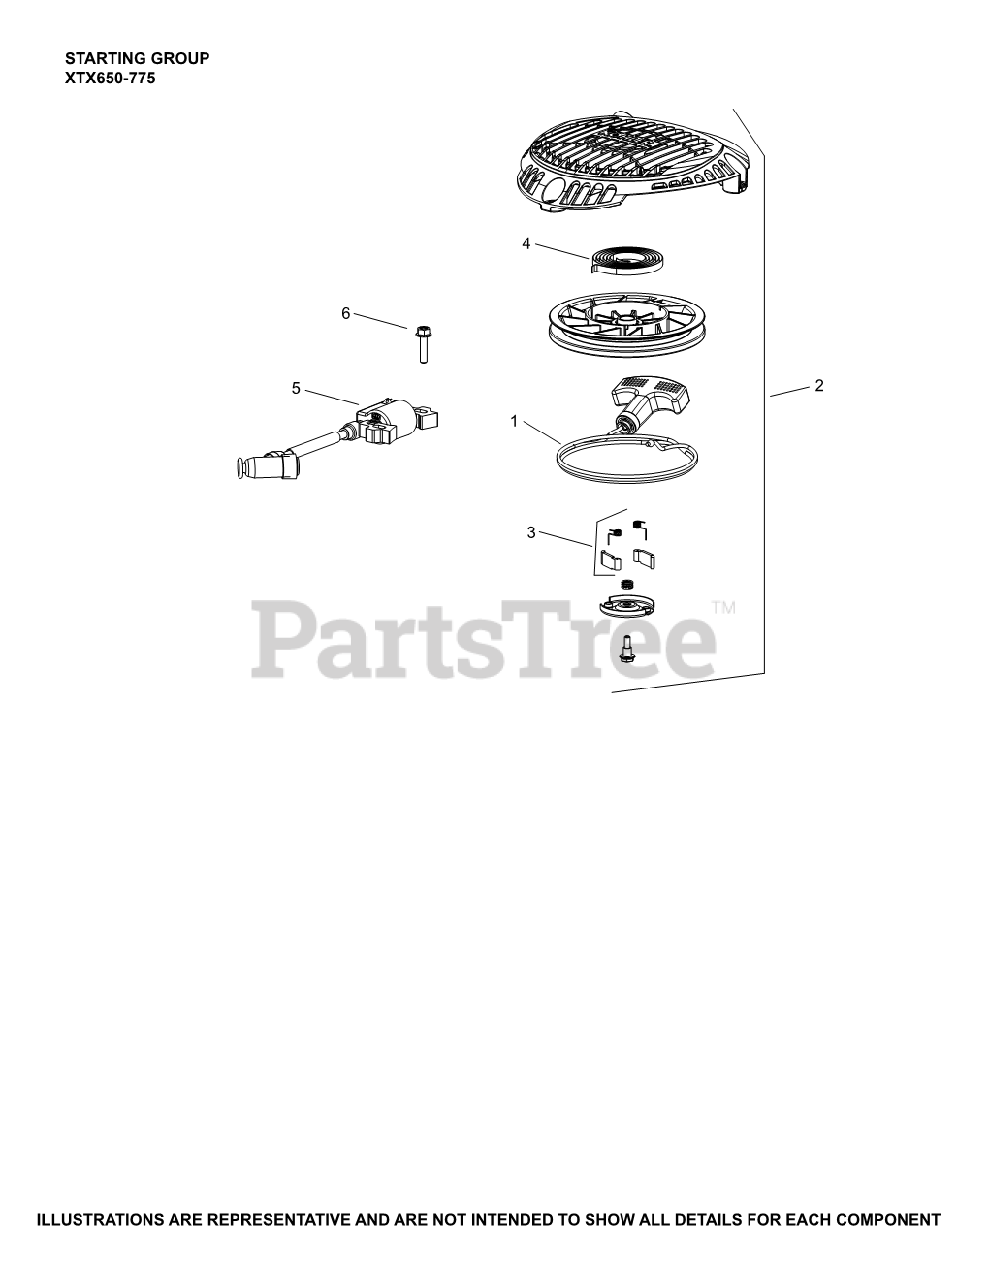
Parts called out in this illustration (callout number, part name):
1	KIT, STARTER ROPE W/HANDLE
2	STARTER ASSY-RETRACT - (#1416521S)
3	KIT, PAWL REPAIR
